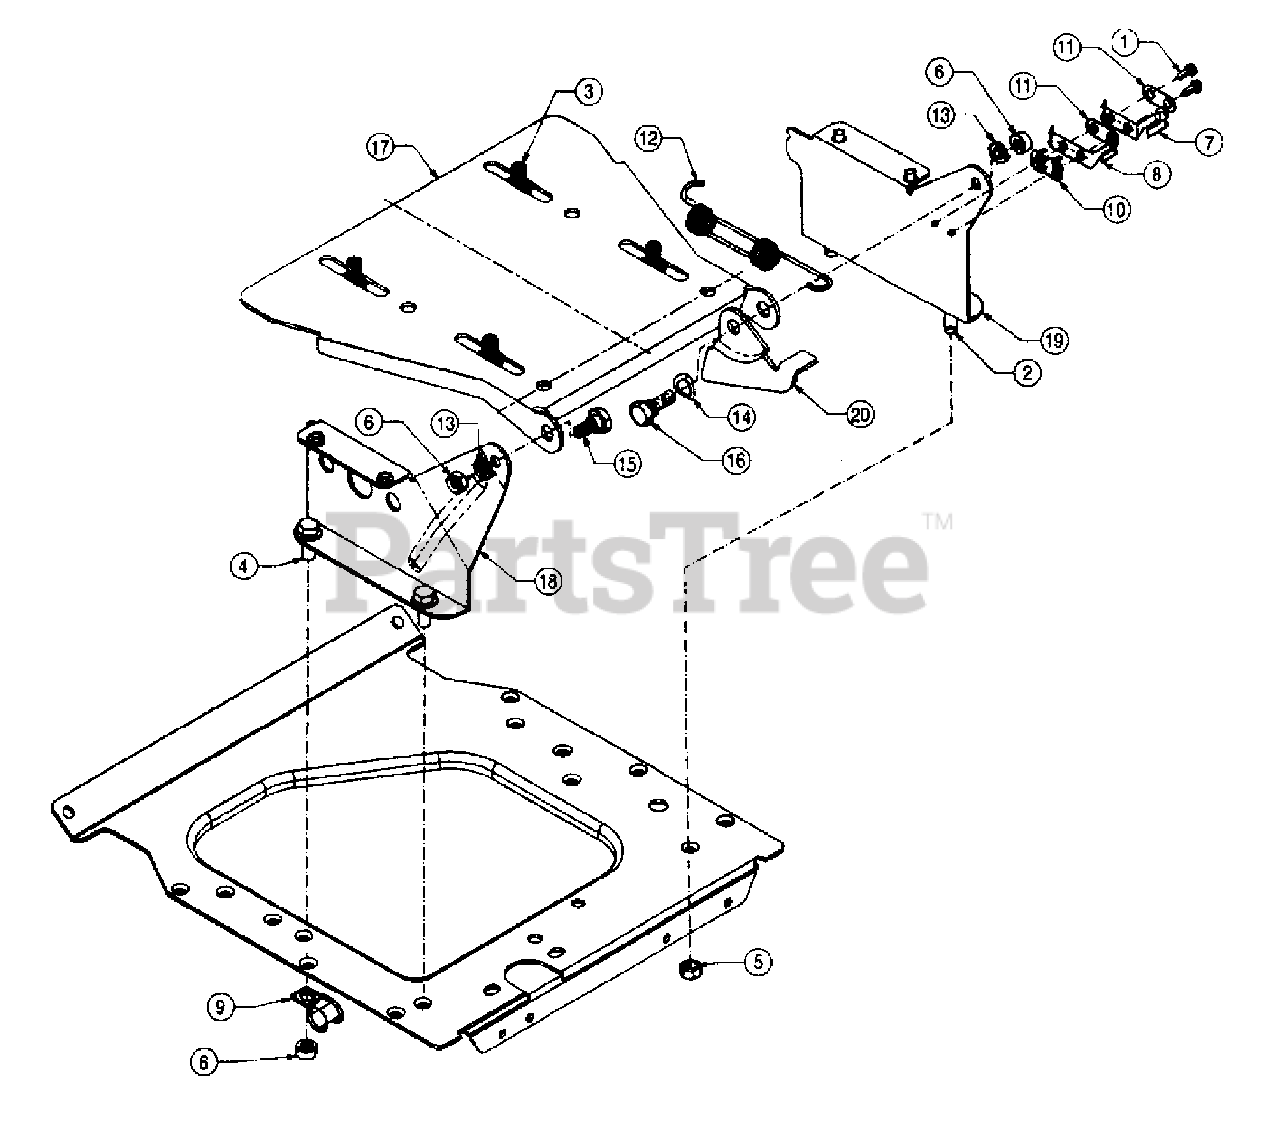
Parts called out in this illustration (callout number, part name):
1	Hex AB-Tap Scr. #8 x .5" Lg.
2	Hex TT-Tap Scr. 5/16-18 x 1.25"
3	Hex TT-Tap Scr. 3/8-16 x .62"
4	Hex Flange Scr. 5/16-24 x .75"
5	Hex L-Nut 5/16-18 Thd.
6	Hex Nut 5/16-18 Thd. (Gr. 8)
7	Seat Safety Switch
8	Seat Safety Switch
9	Clamp
10	Insulator Boss Plate
11	Insulator Plate
12	Ext. Spring 5.31" Lg.
13	L-Wash. 5/16" I.D.
14	Spr. Wash. 7/16" I.D.
15	Shld. Bolt .437" x .56" Lg.
16	Shld. Bolt .437" x .27" Lg.
18	Seat Pivot Support-R.H.
19	Seat Pivot Support-L.H.
20	Seat Lift Brkt.
